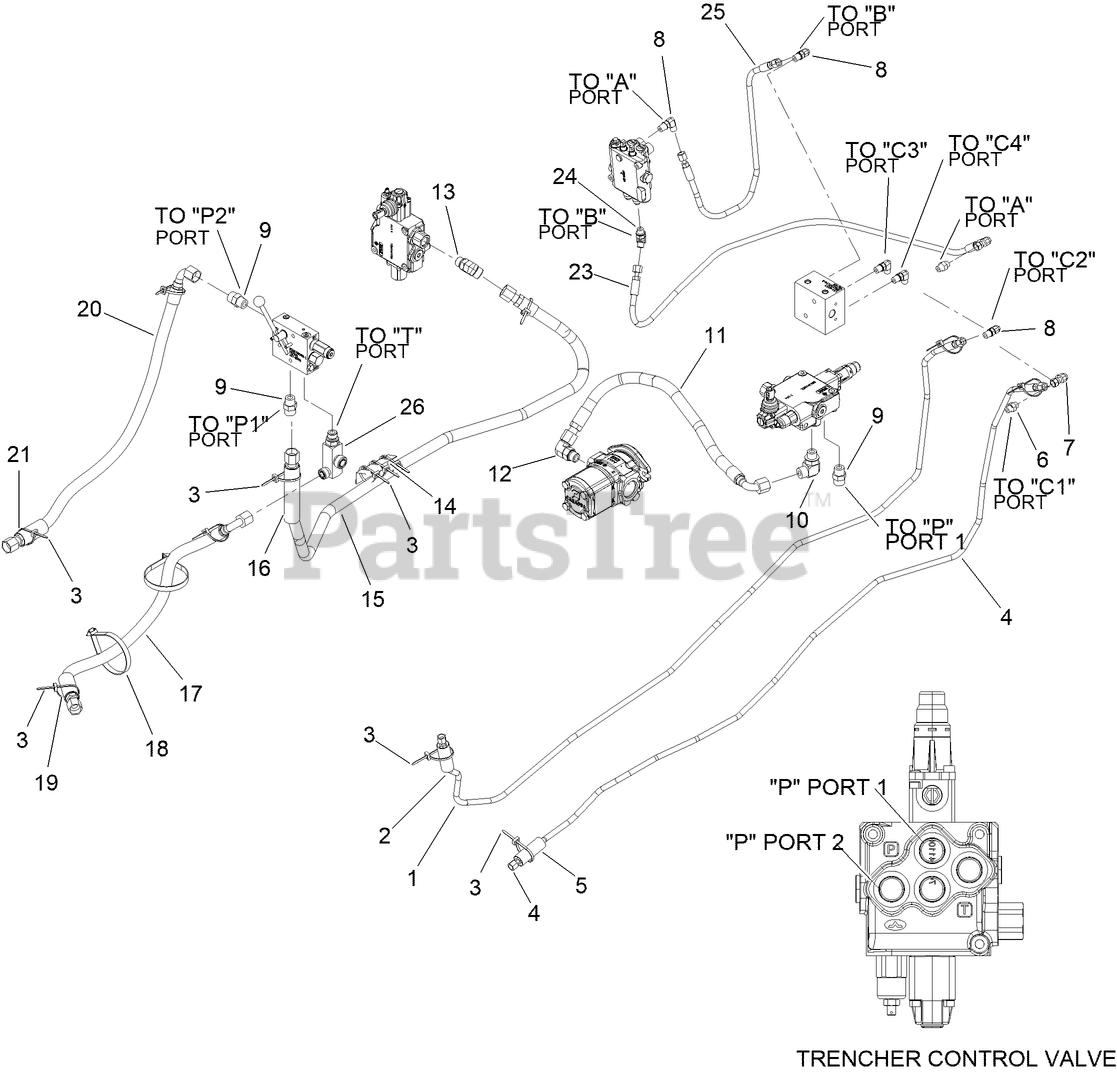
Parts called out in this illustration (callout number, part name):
1	HOSE (04OFX-92.5"-3000)
2	ABRASION SLEEVE (1.00" X 92")
3	TIE-CABLE
4	HOSE (04OFX-82"-3000)
5	ABRASION SLEEVE (1.00" X 82")
6	CONNECTOR (04O-06S)
7	UNION (04O-04OFX90)
8	CONNECTOR (04O-06S90)
9	CONNECTOR (10S-10O)
10	CONNECTOR (10S-10O90)
11	HOSE (10OFX90S-26.5"-3000)
12	CONNECTOR (10S-10O90)
13	CONNECTOR (10S-10O45)
14	PROTECTOR-HOSE
15	HOSE (10OFX-64"-3000)
16	ABRASION SLEEVE (1.25" X 64")
17	HOSE (10OFX90S-33"-3000)
18	CABLE TIE (1/2") 20" LG
19	ABRASION SLEEVE (1.25" X 33")
20	HOSE (10OFX90S-36"-3000)
21	ABRASION SLEEVE (1.25" X 37")
23	HOSE (04OFX-32"-3000)
25	HOSE (04OFX-27"-3000)
26	CONNECTOR (10S-10O-12O)
